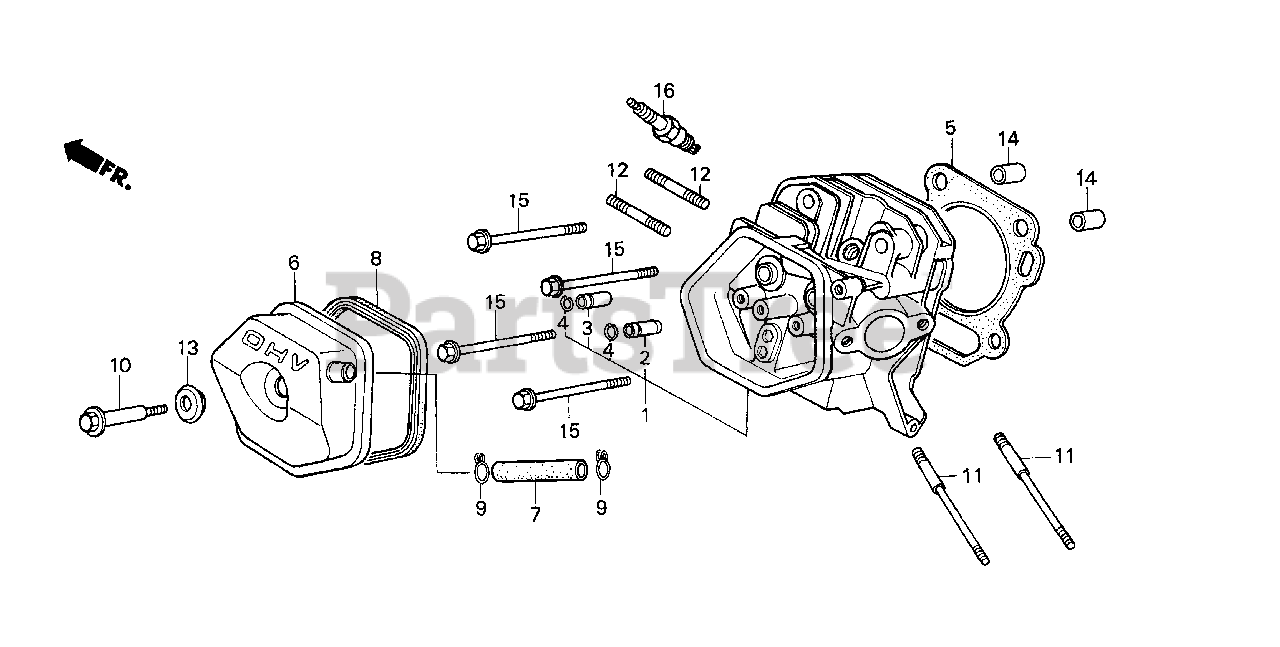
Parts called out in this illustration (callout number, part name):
1	CYLINDER HEAD
2	GUIDE, VALVE (OS)
3	GUIDE, EX. VALVE (OS)
4	CLIP, VALVE GUIDE
5	GASKET, CYLINDER HEAD
6	COVER, HEAD (BREATHER TUBE JOINT)
7	TUBE, BREATHER
8	GASKET, HEAD COVER
9	CLIP, BREATHER TUBE
10	BOLT, HEAD COVER
11	BOLT, STUD (8X131.5)
12	BOLT, STUD (8X40)
13	WASHER, HEAD COVER
14	PIN, DOWEL (12X20)
15	BOLT, FLANGE (10X80)
16	SPARK PLUG (BPR5ES) (NGK)
16	SPARK PLUG (W16EPR-U) (DENSO)
16	SPARK PLUG (BPR6ES) (NGK)
16	SPARK PLUG (W20EPR-U) (DENSO)
